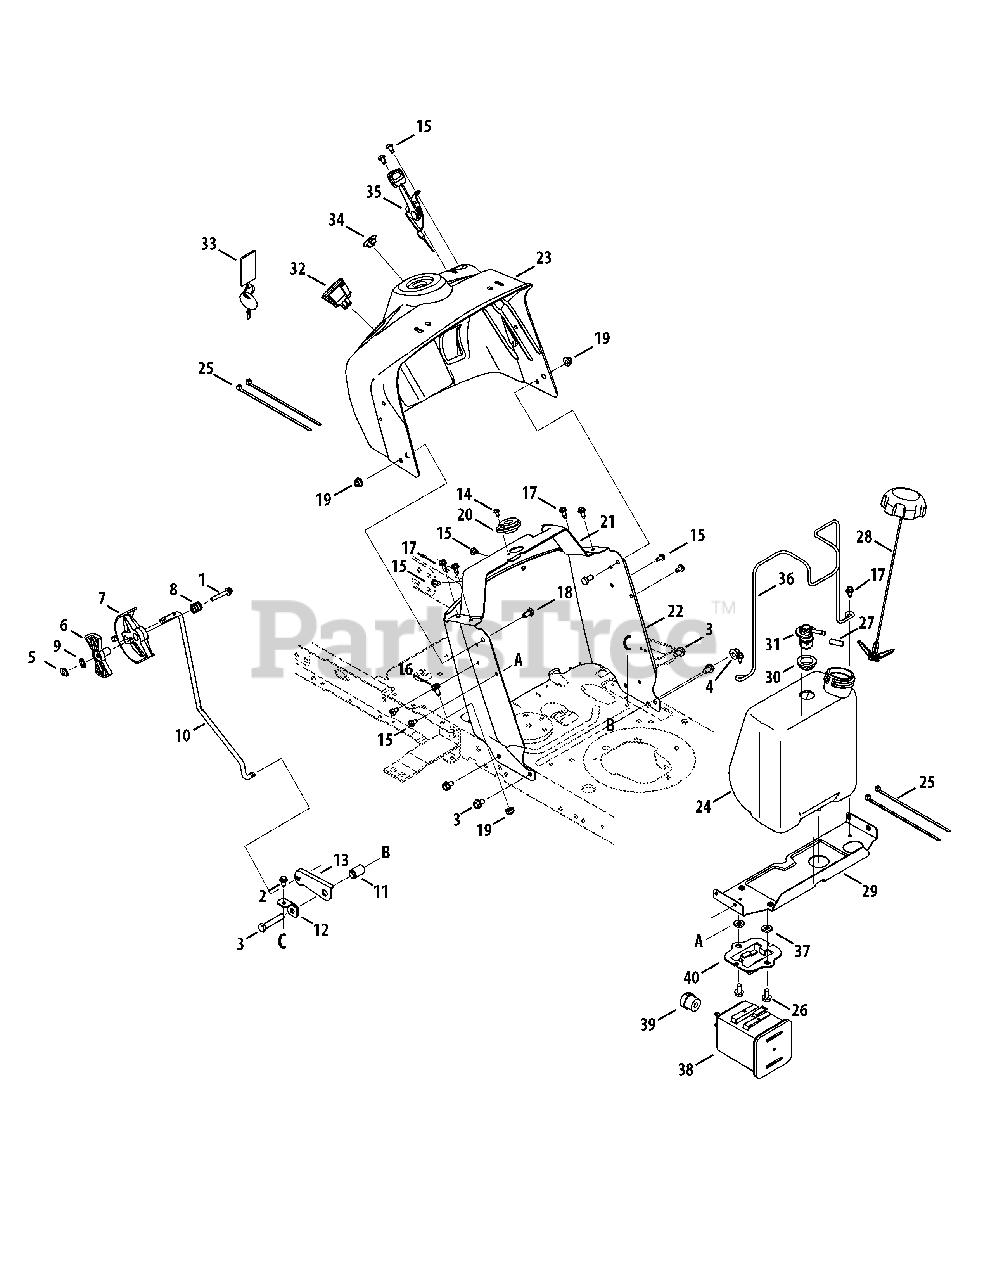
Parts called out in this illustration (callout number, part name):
1	Hex Head Screw, 1/4-20 x 1.50
2	Self-Tap Screw, 1/4-20 x .625
3	Hex Head Screw, 3/8-16 x 2.00
4	Flange Lock Nut, 3/8-16
5	Top Lock Weld Nut, 1/4-20
6	Index Control
7	Shift Lever
8	Compression Spring, .685 x .63
9	Internal Lock Washer, 1/4
10	Speed Control Rod
11	Flange Spacer, .390 x .671 x 1.095
12	Speed Latch Tab
13	Speed Latch
14	Screw, #10
15	Self-Tap Screw, 1/4-20
16	Self-Tap Screw, 5/16-18
17	Hex Washer Screw, 1/4-20 x .625
18	Hex Head Screw, 5/16-18
19	Flange Lock Nut, 5/16-18
20	Steering Column Bearing
21	Steering Support Bracket
22	Lower Dash
23	Upper Dash Panel
24	Fuel Tank
25	Cable Tie, 3/16 x 7.4"
26	Screw, 5/16-18 x .750
27	Vent Hose
28	Fuel Cap
29	Gas Tank Support Bracket
30	Rubber Grommet
31	Fuel Rollover Valve
32	Key Switch Module
33	Key Assembly
34	Choke Plug
35	Throttle/Choke Assembly
36	Fuel Tank Support Rod
37	Flat Washer, .344 x .750 x .120
38	Carbon Canister
39	Canister Vent Filter
40	Canister Adaptor Bracket
